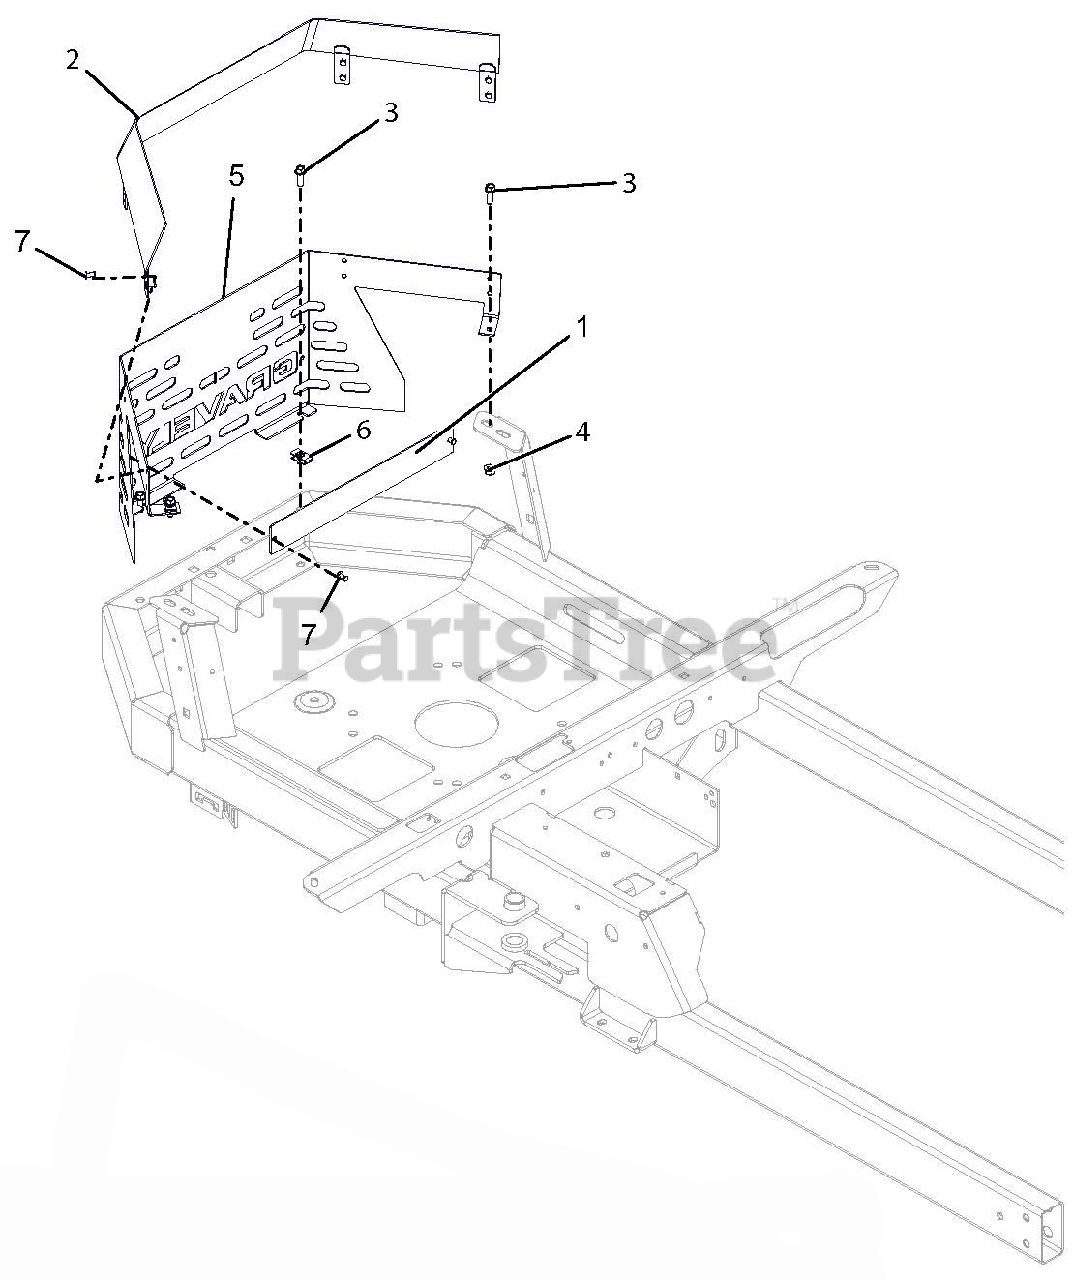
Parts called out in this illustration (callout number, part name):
1	PLATE, SHROUD BACKER
2	WLDMT, ENGINE SHROUD TOP TRIM
3	BLT-HEX .25-20X.75 HWH YWZC GR5
4	NUT, LK-TOP-FLG .25-20 YWZC
5	SHROUD, ENGINE GRAVELY
6	NUT, RTNR .25-20 X .56
7	RVT-POP .187x.375 (#66) BLACK
